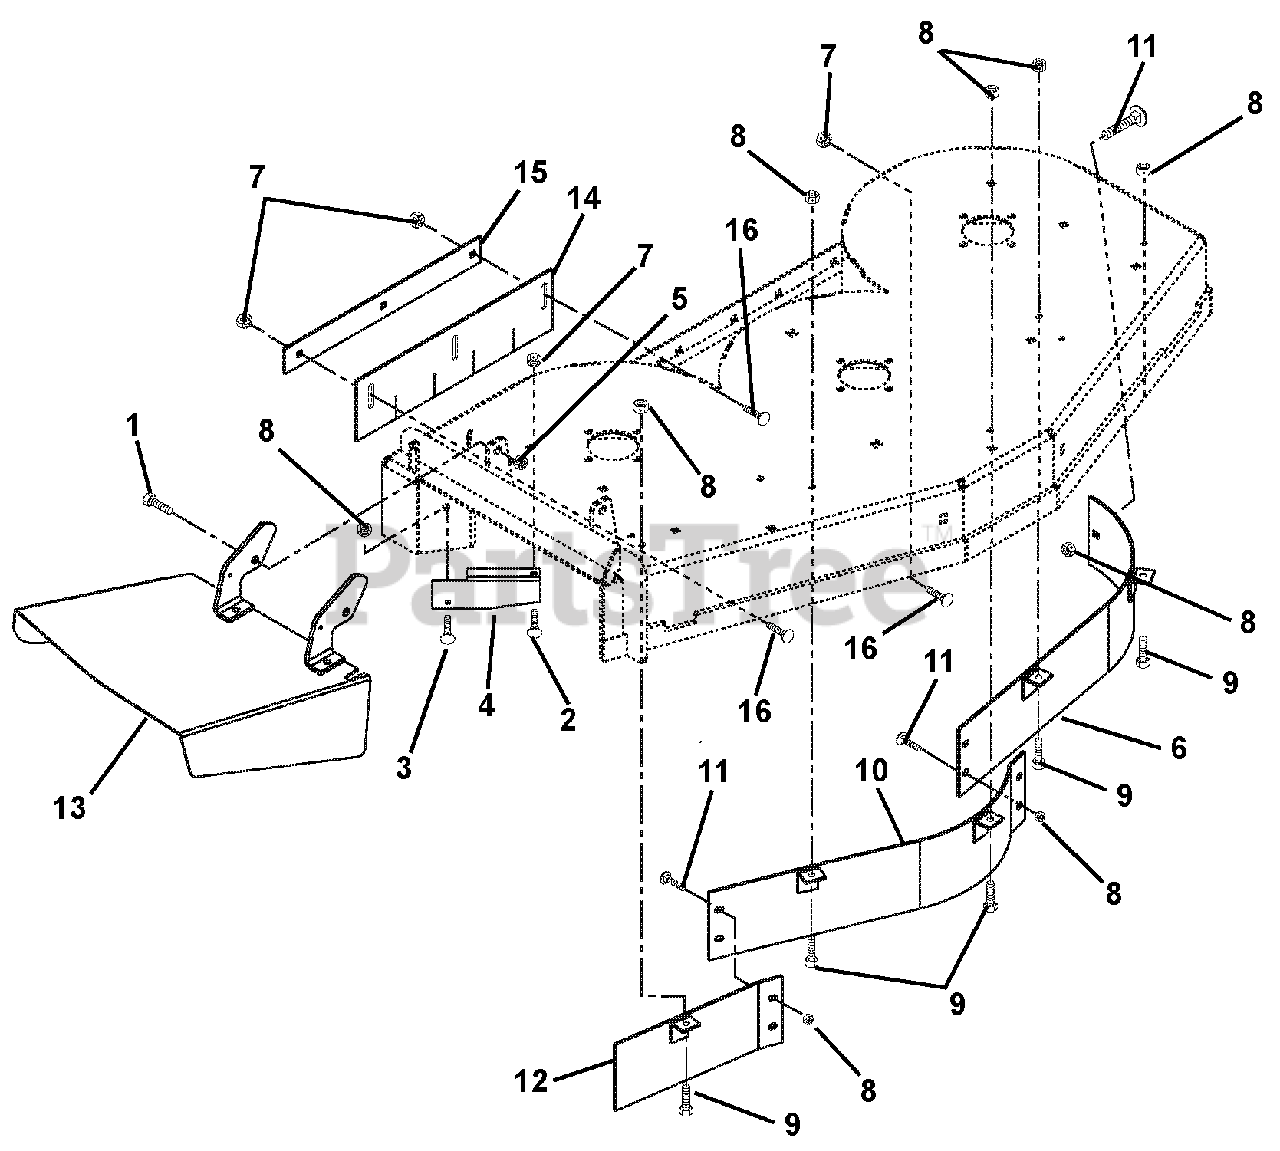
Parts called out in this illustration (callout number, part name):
1	Bolt-Hex .50-13 x 1.25 Grade 5
2	Bolt-Round Head Square Neck .38-16 x .75 Grade 5
3	Bolt-Round Head Square Neck .31-18 x 1.00 Grade 5
4	Deflector 44"/48" (106, 107, 108, 113, 116)
5	Nut-Locking-Nylon .50-13
6	Weldment- Upper Baffle Left (106, 107, 108, 116)
7	Nut-Locking-Top-Flange .38-16
8	Nut-Locking-Top-Flange .31-18
9	Bolt-Hex .31-18 x .75 Grade 5
10	Weldment- Upper Baffle Center (106, 107, 108, 116)
11	Bolt-Round Head Square Neck .31-18 x .75 Grade 5
12	Weldment, Right Hand Baffle-Upper (106, 107, 108, 116)
13	Chute-Discharge
14	Skirt- Rubber
15	Strip- Striper Mount
16	Bolt-Round Head Square Neck .38-16 x 1.00 Grade 5
